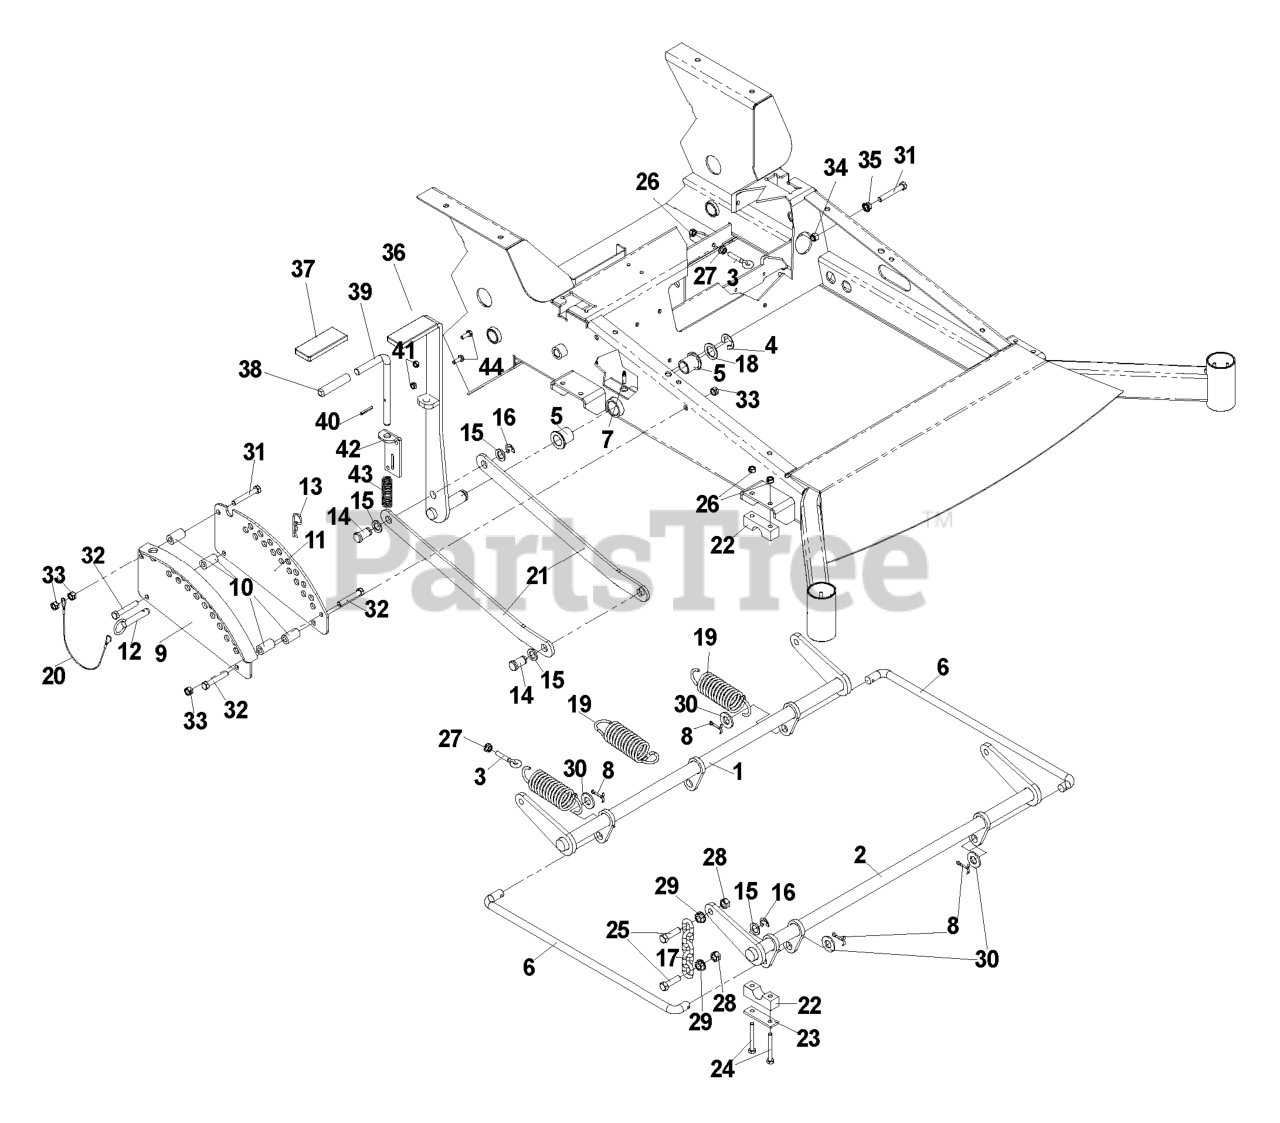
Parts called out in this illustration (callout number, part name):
1	SHAFT LIFT REAR
2	LIFT SHAFT
3	EYEBOLT, RH
4	E-RING 7/8
5	BUSHING, FLANGED
6	CONNECTING LINK
7	GREASE ZERK LONG
8	COTTER PIN
9	ADJ. PLATE WLDMNT
10	DECK LIFT SPACER
11	ADJ. PLATE PAINTED
13	HAIRPIN #4
14	CLEVIS PIN
15	BUSHING
16	E-RING 5/8
17	LIFT CHAIN
18	BSHG .875 X 1.375 X .074 ZD
19	DECK LIFT SPRING
21	LIFT LINKAGE,PAINTED
22	PILLOW BLOCK
23	REINFORCEMENT BAR
24	BOLT 5/16C X 2 1/2
25	HCS 7/16C X 1 1/2
26	NUT 5/16C CENTERLOCK
27	NUT 5/16C WHIZ
28	NUT 7/16C CENTERLOCK
29	NUT 7/16C WHIZ
30	WASHER 5/8 FLAT
31	HCS 3/8C X 2 1/2
32	HCS 3/8C X 2 1/4
33	NUT 3/8C CENTERBLOCK
34	NUT 3/8-16 NYLOC
35	NUT 3/8C WHIZ
36	LIFT LEVER WELDMENT
41	NUT 1/4C CENTER LOCK
42	PIN MT, UPPER
44	HCS 1/4C X 3/4 HCS
